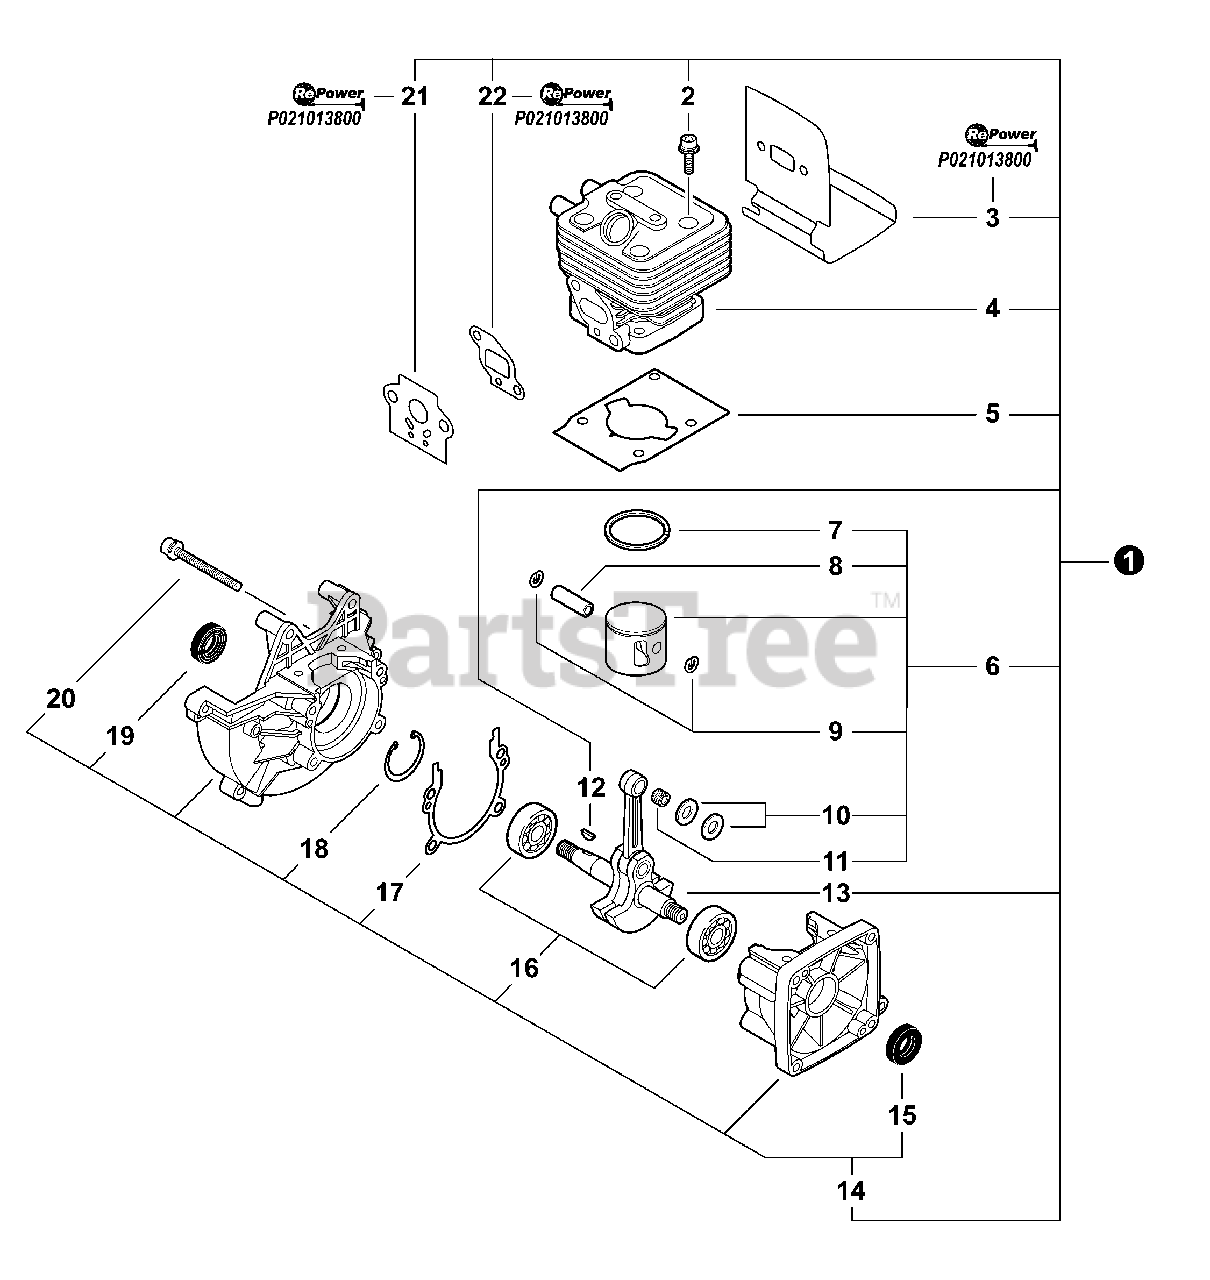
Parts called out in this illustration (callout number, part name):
1	SHORT BLOCK
2	SCREW 5×25
3	HEAT SHIELD, EXHAUST
4	CYLINDER
5	GASKET, CYLINDER
6	PISTON KIT
7	RING, PISTON
8	PIN, PISTON
9	RING, SNAP
10	WASHER, THRUST 8
11	BEARING, NEEDLE 9
12	KEY, WOODRUFF
13	CRANKSHAFT ASSY
14	CRANKCASE KIT
15	SEAL, OIL 12
16	BEARING, BALL - 6201 C3
17	GASKET, CRANKCASE
18	RING, SNAP Ø32
19	SEAL, OIL 12
20	BOLT 5×28
21	GASKET, INTAKE
22	GASKET, INTAKE
